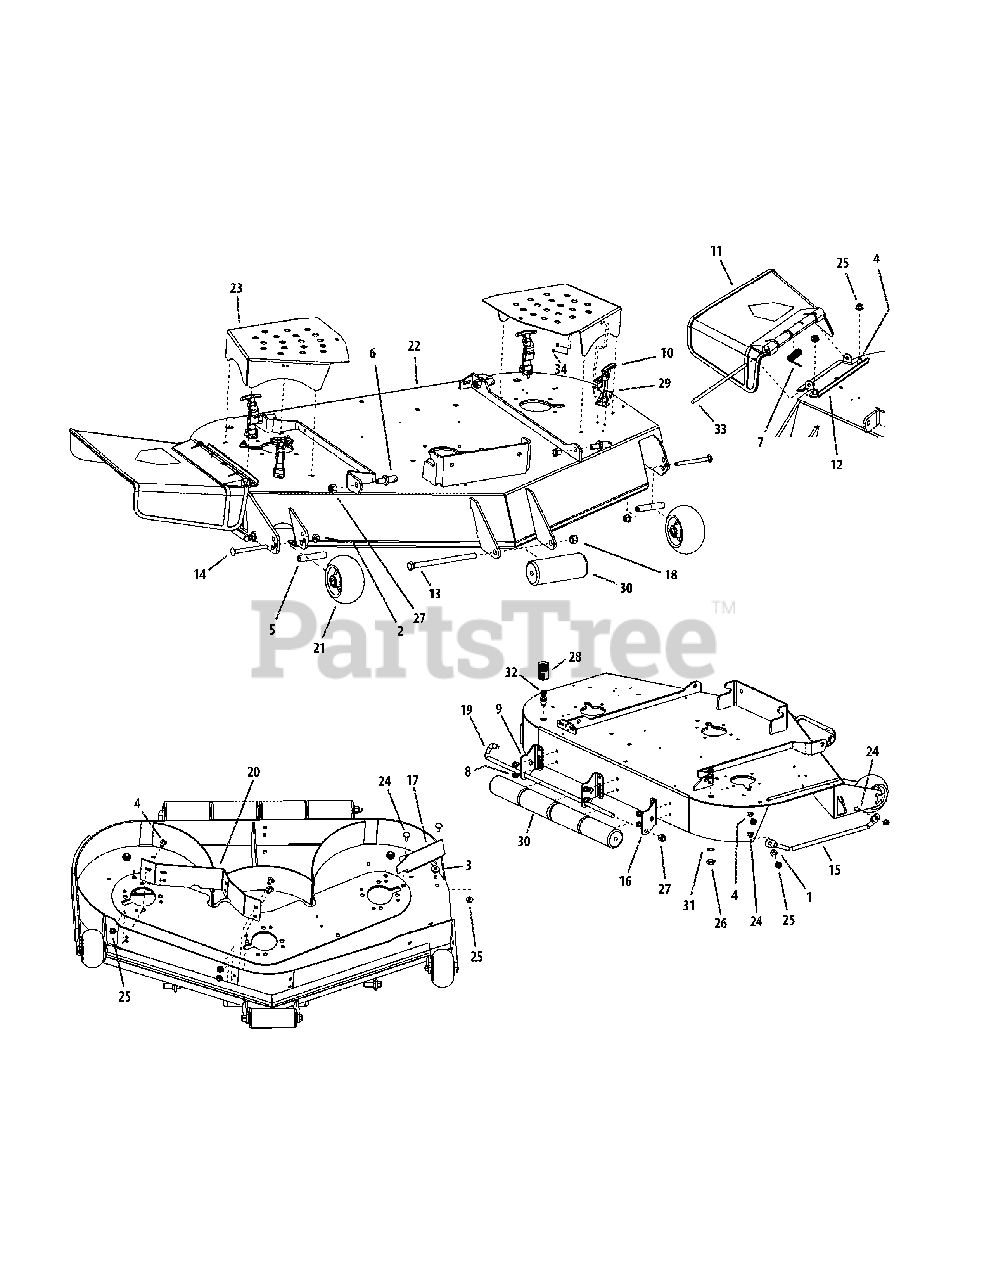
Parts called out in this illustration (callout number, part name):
1	Flat Washer, 3/8
2	Flange Lock Hex Nut, 3/8-16
3	Idler Washer
4	Carriage Bolt, 3/8-16 x .75 Lg.
5	Wheel Spacer
6	Pin, 5/8 Dia. x 1.2 Lg.
7	Torsion Spring, 0.4ID x 2.16Lg
8	Hex Index Washer Screw, 3/8-16, .05
9	Deck Roller Mount Bracket
10	T-Handle Latch Draw
11	Deflector Chute
12	Deflector Chute Bracket
13	Hex Cap Screw, 1/2-20 x 7.50
14	Carriage Bolt, 3/8-16 x 4.00
15	Finger Guard
16	Deck Roller Mount Bracket, Right
18	Lock Nut, Nylon Insert, 1/2-20
19	J-Hook w/ Threaded Roller
20	48" Adjustment Baffle
21	Complete Wheel, 5.00 Dia.
22	48" Deck Assembly
23	Deck Belt Cover
24	Carriage Bolt, 3/8-16 x 1
25	Lock Nut, Nylon Insert, 3/8-16
26	Hex Nut, M16-1.5
27	Lock Nut, Nylon Insert, 1/2-13
28	Water Nozzle Adaptor
29	Phillips Head Screw, #10-32 x 1/2
30	Front Roller
31	Lock Washer, 17 x 23.8 x 1.95
32	Deck Water Nozzle
33	Chute Deflector Rod
34	Lock Nut, Nylon Insert, #10-32
